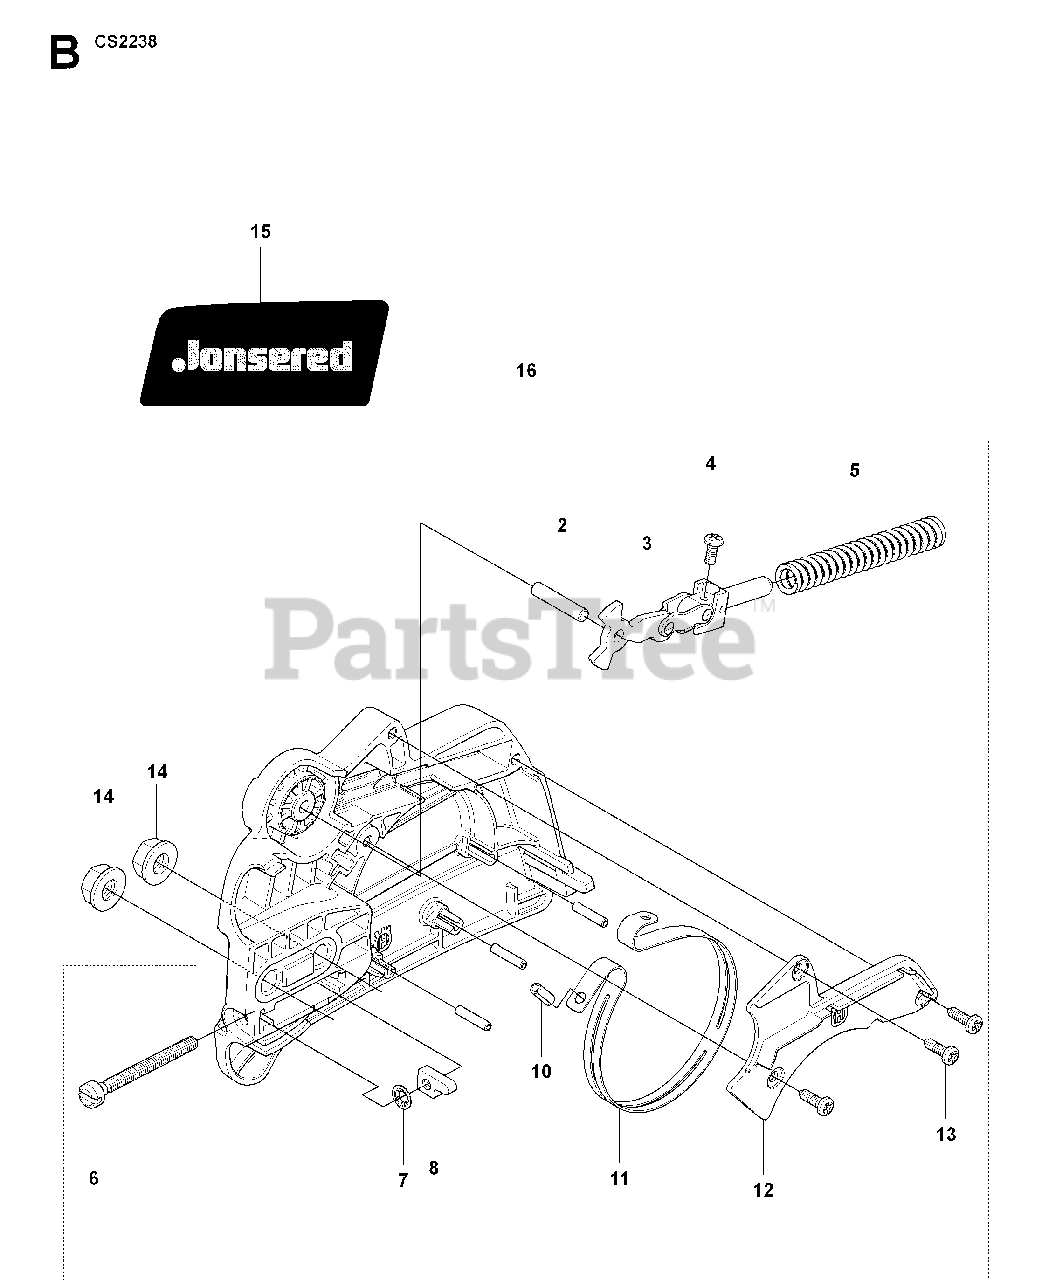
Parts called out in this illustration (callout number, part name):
3	FRONT LINK ASSY
4	SCREW
6	SCREW
8	ADJUST PIN,BAR 36/41
11	BRAKE BAND
